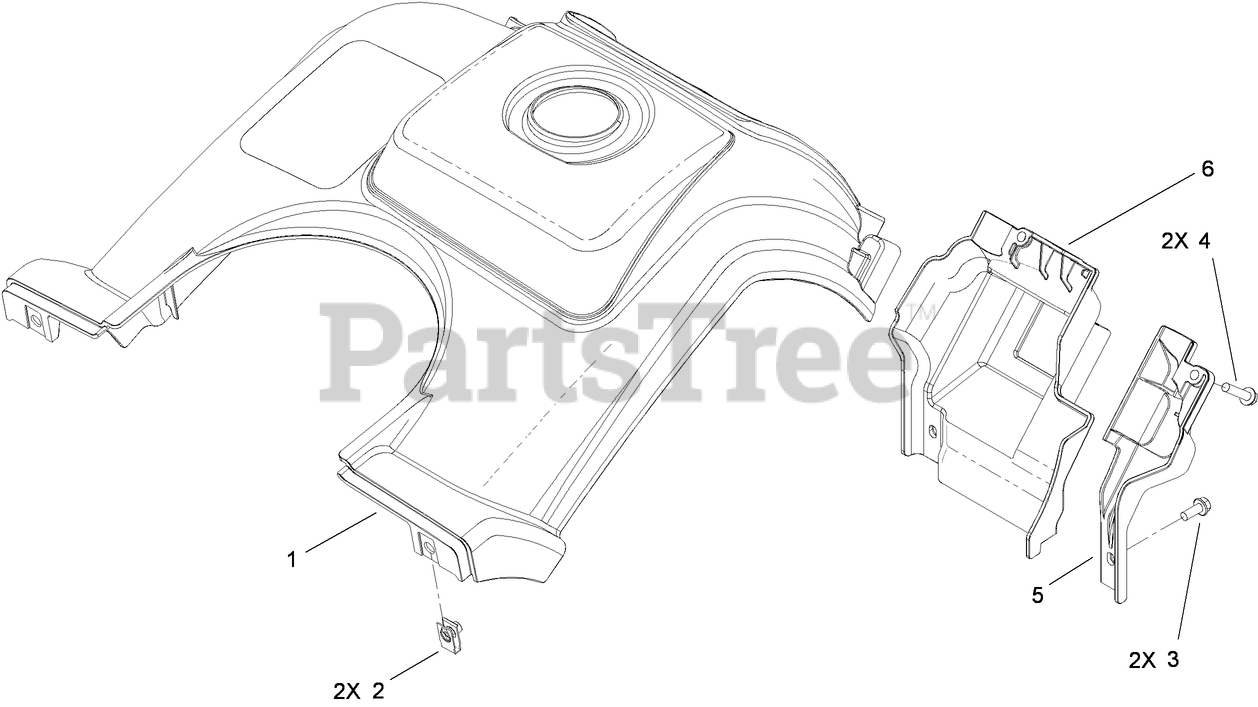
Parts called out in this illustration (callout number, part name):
1	SHROUD ASM
3	SCREW-HWH
4	SCREW-PLASTIC
5	SHROUD-LOWER, LH
6	SHROUD-LOWER, RH
